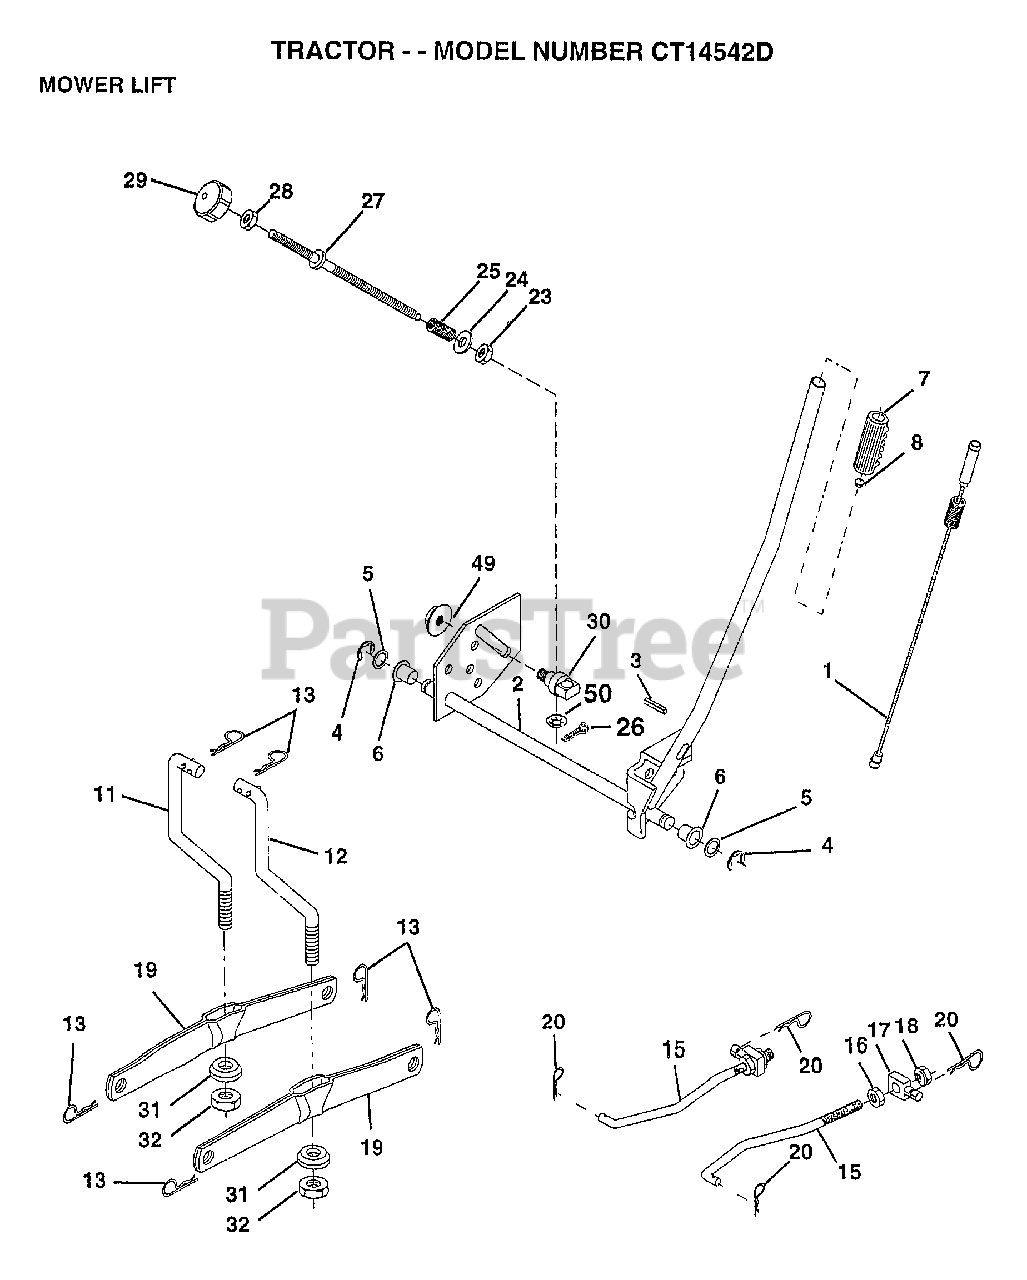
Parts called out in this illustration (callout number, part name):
1	WIRE.ASM.INNER.SP
2	"SHAFT AMS LIFT,RH"
3	PIN GROOVE
5	WASHER
6	NYLON BEARING
7	GRIP
15	LINK.FRONT
16	NUT
17	TRUNION
18	NUT.LK.W/WSH.1/2.
19	ARM SUSP REAR
20	RETAINER.SPRING
23	NUT T
24	WASHER
25	SPRING.COMP.INF.H
27	ROD.ADJ.LIFT
28	NUT
29	KNOB INF 3/8-16
30	TRUNNION
31	BEARING PVT LH
32	NUT.CROWNLOCK.3/8
49	NUT.HXFLG.LOCK.
50	NUT PUSH M
